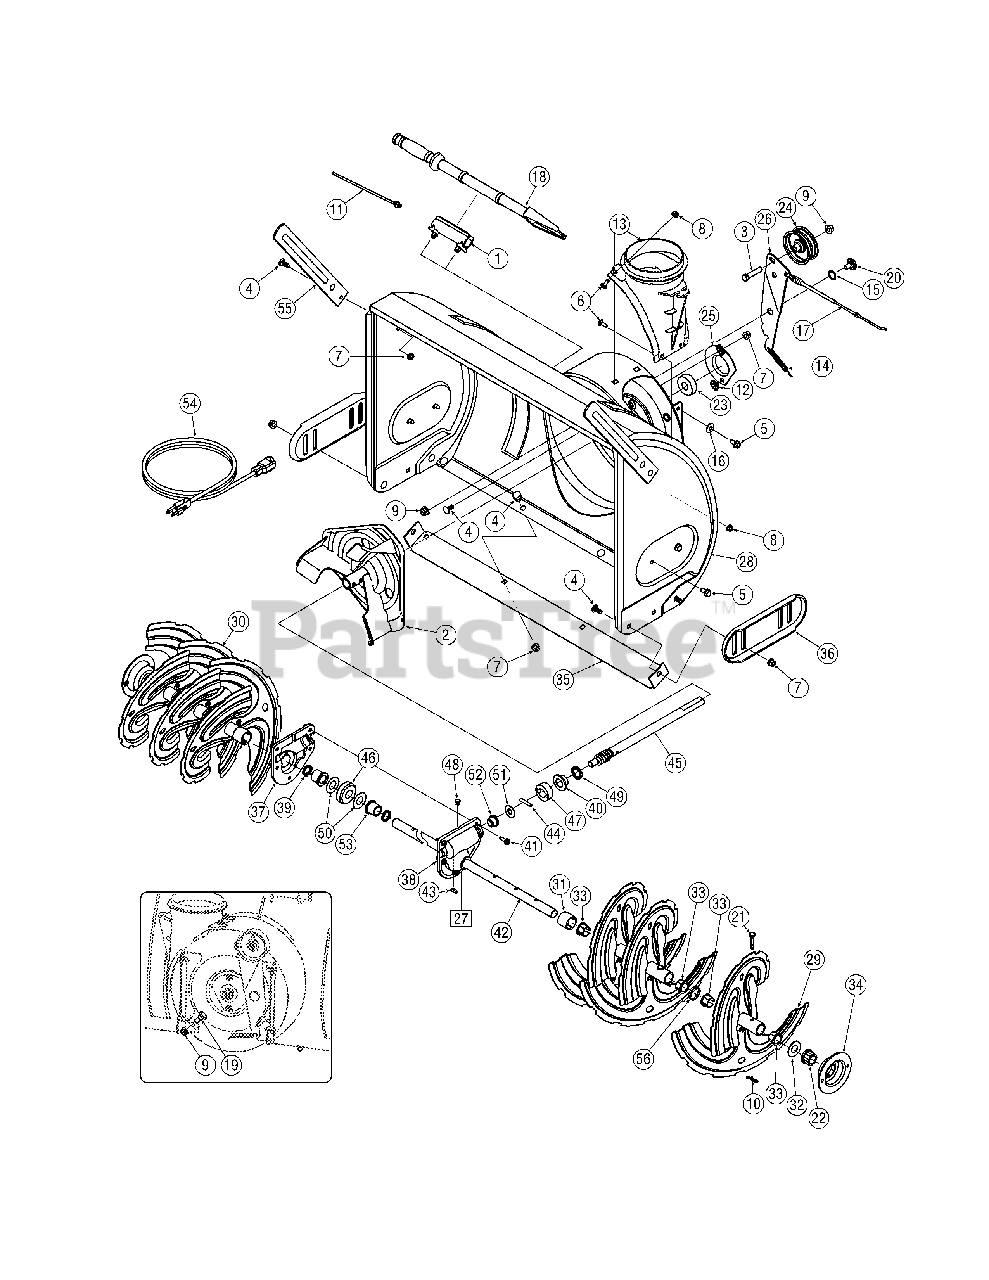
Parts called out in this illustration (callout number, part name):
1	Snow Removal Tool Mount
2	Impeller Assembly, 12" Dia.
3	Hex Screw, 3/8-16, 1.75, Gr5
4	Bolt, Carriage, 5/16-18, .750 Gr1
5	Screw, 5/16-18, 0.750
6	Screw, Carriage, 1/4-20, .750, Gr5
7	Nut, Flange Lock, 5/16-18, Nylon
8	Nut, Flange Lock, 1/4-20, Nylon
9	Nut, Flange Lock, 3/8-16, Nylon
10	Cotter Pin, Bow-tie
11	Cable, Tie, 3/16 x .05 x 7.4
12	Nut, Push-on, .25 Dia
13	Chute, Adapter 5" Dia
14	Spring, Extension, .38 OD x 4.59
15	Washer, Wave, .625 x .885 x .015
16	Washer, Bell, .340 x .872 x .060
17	Clutch Cable, Auger, 47.23"
18	Snow Removal Tool
19	Screw, Shoulder, .498 x .34, 3/8-16
20	Screw, Shoulder, .625 x .17, 3/8-16
21	Shear Pin, .25 x 1.50
22	Bearing, Hex Flange x .75 ID
23	Bearing, Ball, .75 ID x 1.85 OD
24	Flat Pulley, Idler, 2.75 OD
25	Housing, Bearing, 1.85 ID
26	Bracket, Auger Idler w/ Brake
27	Gearbox Assembly, Auger, 30"
28	Housing Assembly, Auger 30"
29	Spiral Assembly, LH
30	Spiral Assembly, RH
31	Spacer, 1.25 OD x .75 ID x 1.00
32	Washer, Flat, .76 x 1.49 x .06
33	Bushing, Flange, .80 ID x .91 OD
34	Housing, 1" Hex Bearing
35	Shave Plate, 2.25 x 29.66
36	Slide Shoe
37	Housing, Auger, RH Reduced
38	Housing, Auger, LH Reduced
39	Seal, Oil, .750 x 1.00 x .125
40	Bearing, Flange, .75 x 1.0 x .59
41	Screw, Self-tapping, 1/4-20, 0.750
42	Axle, Auger, 30"
43	Key, Hi-pro 3/16 x 5/8
44	Pin, Dowel, .25 OD x 1.2
45	Shaft, Worm .75 OD
46	Gear, Worm 20T
47	Collar, Thrust
48	Plug, 1/4 x .437
49	Seal, Oil, .75 x 1 x .131
50	Washer, Flat, .760 ID x 1.5 OD
51	Washer, Flat, .51 x 1.12
52	Bearing, Flange, .75 x 1.0 x .925
53	Bearing, Flange, .75 x 1.00 x .975
54	Extension Cord, 110V
55	Drift Cutter
56	Spacer, 1.25 OD x .75 ID x 3/16
